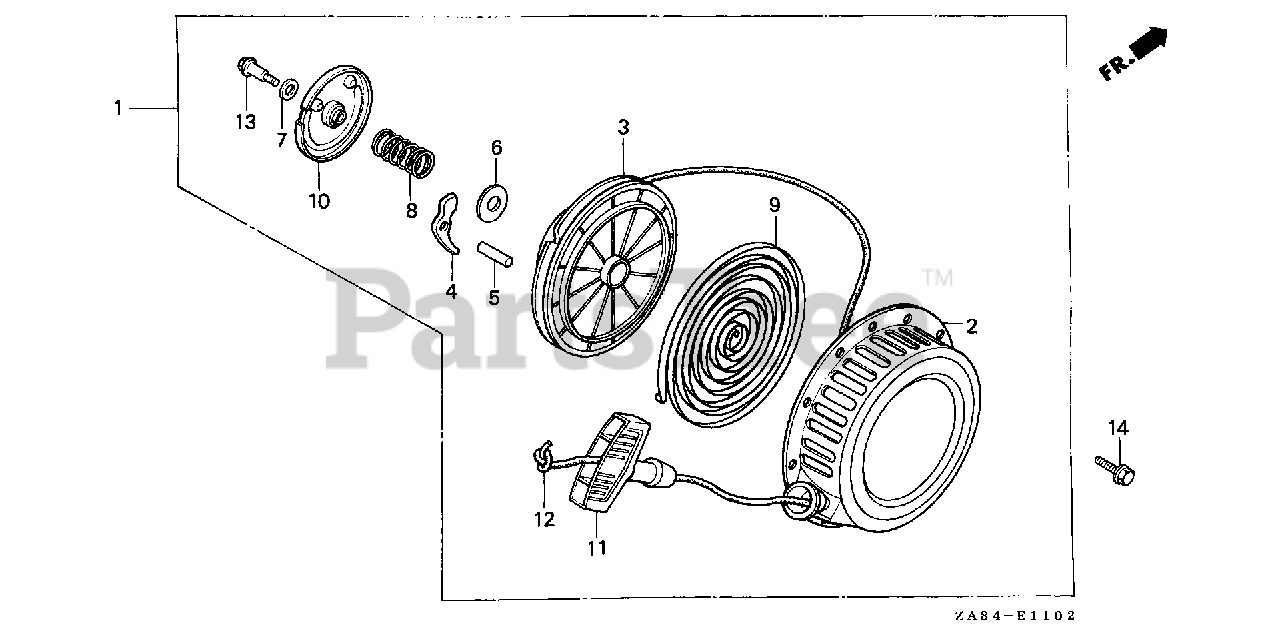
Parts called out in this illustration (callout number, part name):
1	STARTER, RECOIL
2	CASE, STARTER
3	REEL, STARTER
4	RATCHET, STARTER
5	SHAFT, RATCHET
6	PLATE A, FRICTION
7	PLATE B, FRICTION
8	SPRING, FRICTION
9	SPRING, RETURN
10	COVER, REEL STARTER
11	GRIP, STARTER
12	ROPE, STARTER (#4X65") (N/A: USE P/N 08540-ZG921-11)
13	BOLT, REEL COVER
14	BOLT, FLANGE (6X8)
